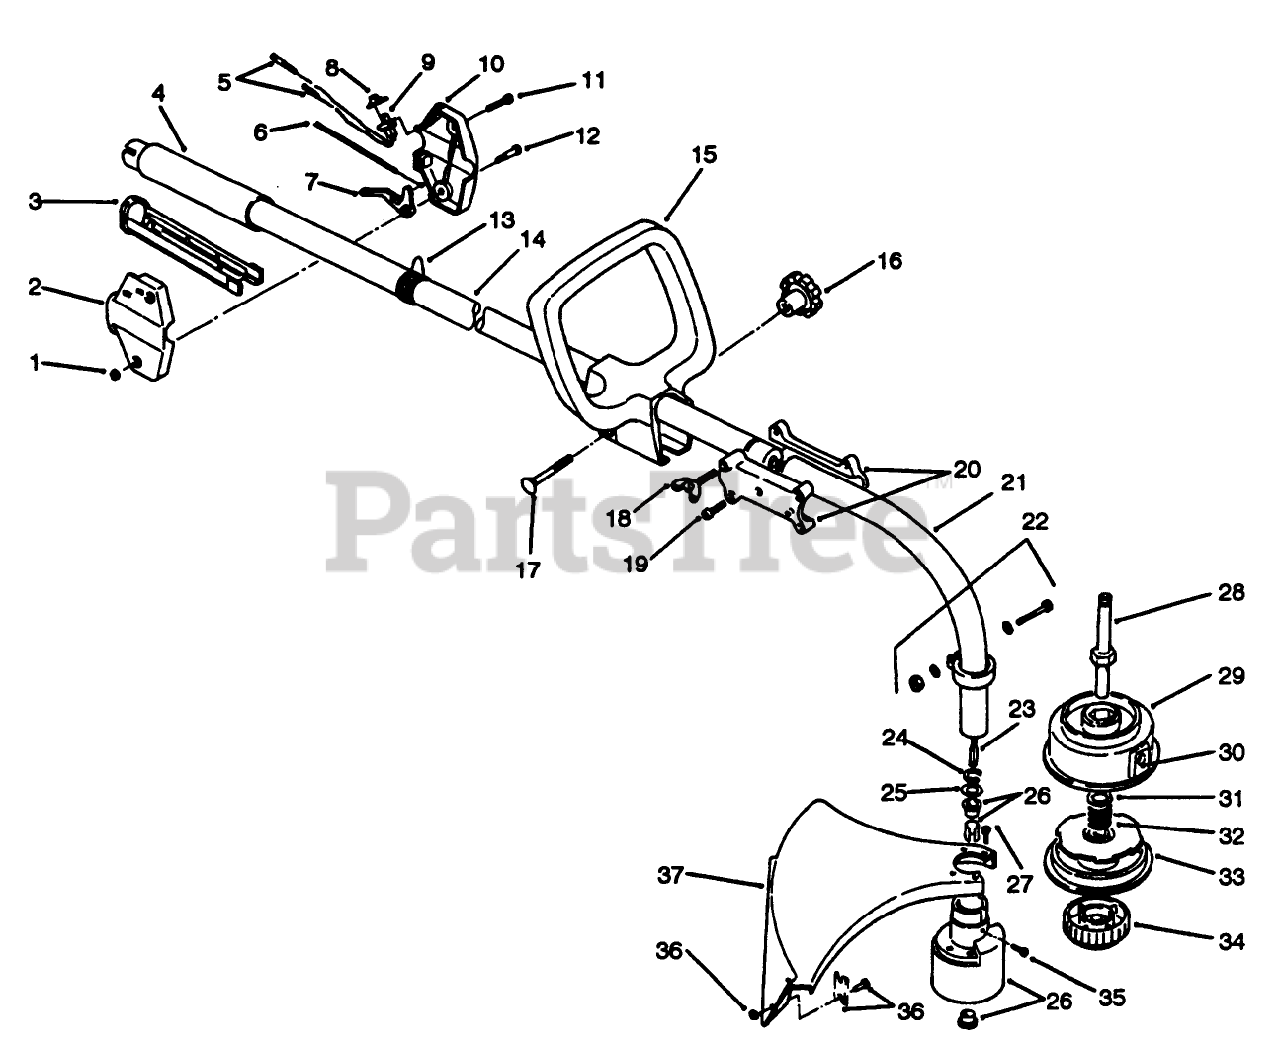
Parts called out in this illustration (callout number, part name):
1	NUT-LOCK, NI
2	RH HOUSING
3	TROUGH 1"
4	GRIP - RUBBER
5	LEAD WIRE ASM
8	SWITCH COVER
9	SWITCH
10	LH HOUSING
12	SCREW-SHOULDER
21	LOWER DRIVE HSG ASM
22	CLAMP ASM - UPPER
24	RETAINING RING
25	WASHER
26	BUSHING HSG ASM
27	GUARD MTG SCREW ASM
29	OUTER SPOOL EYELET ASM
30	EYELET
31	RETAINER WASHER
32	REEL - INNER
33	SPRING
34	KNOB ASSEMBLY-SMALL BUMP
35	ANTI-ROTATION SCREW
36	BLADE ASM
37	GUARD & BLADE ASM
